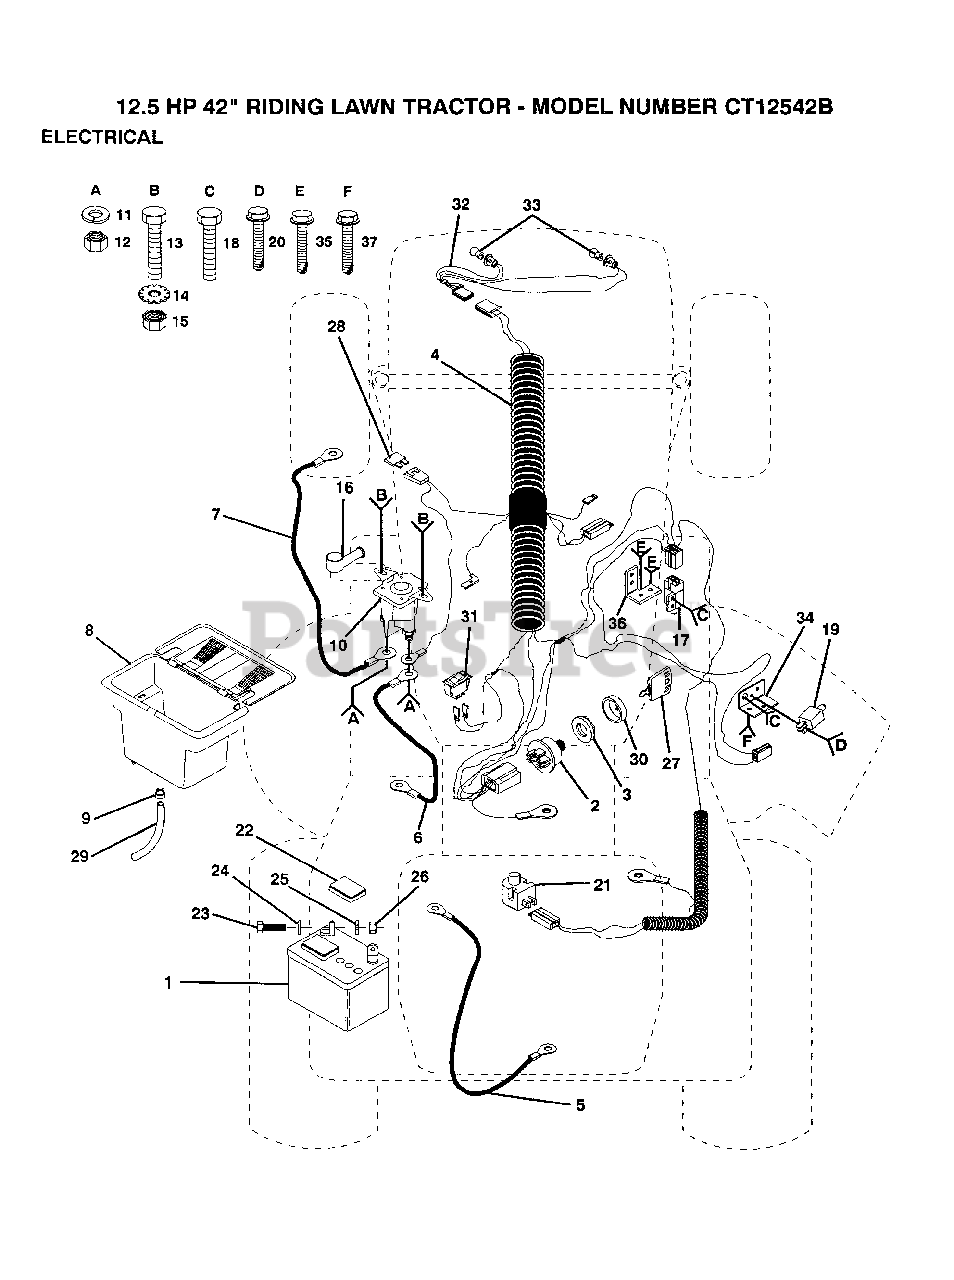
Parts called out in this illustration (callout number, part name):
3	NUT IGNITION
4	IGN HARNESS
5	CABLE T
7	"CABLE T, BATTERY"
9	HOSE CLAMP T
12	NUT
13	BOLT
15	NUT
17	SWITCH INTERLOCKT
18	SCREW
19	SWITCH-INTER. GT
20	SCREW
21	SWITCH SEAT
22	"CAP,BATTERY "
23	BOLT LT
24	WASHER
25	LOCKWASHER
28	FUSE HYT
31	SWITCH LT
34	SWITCH BRACKET
35	SCREW
36	BRACKET LT
37	SCREW
